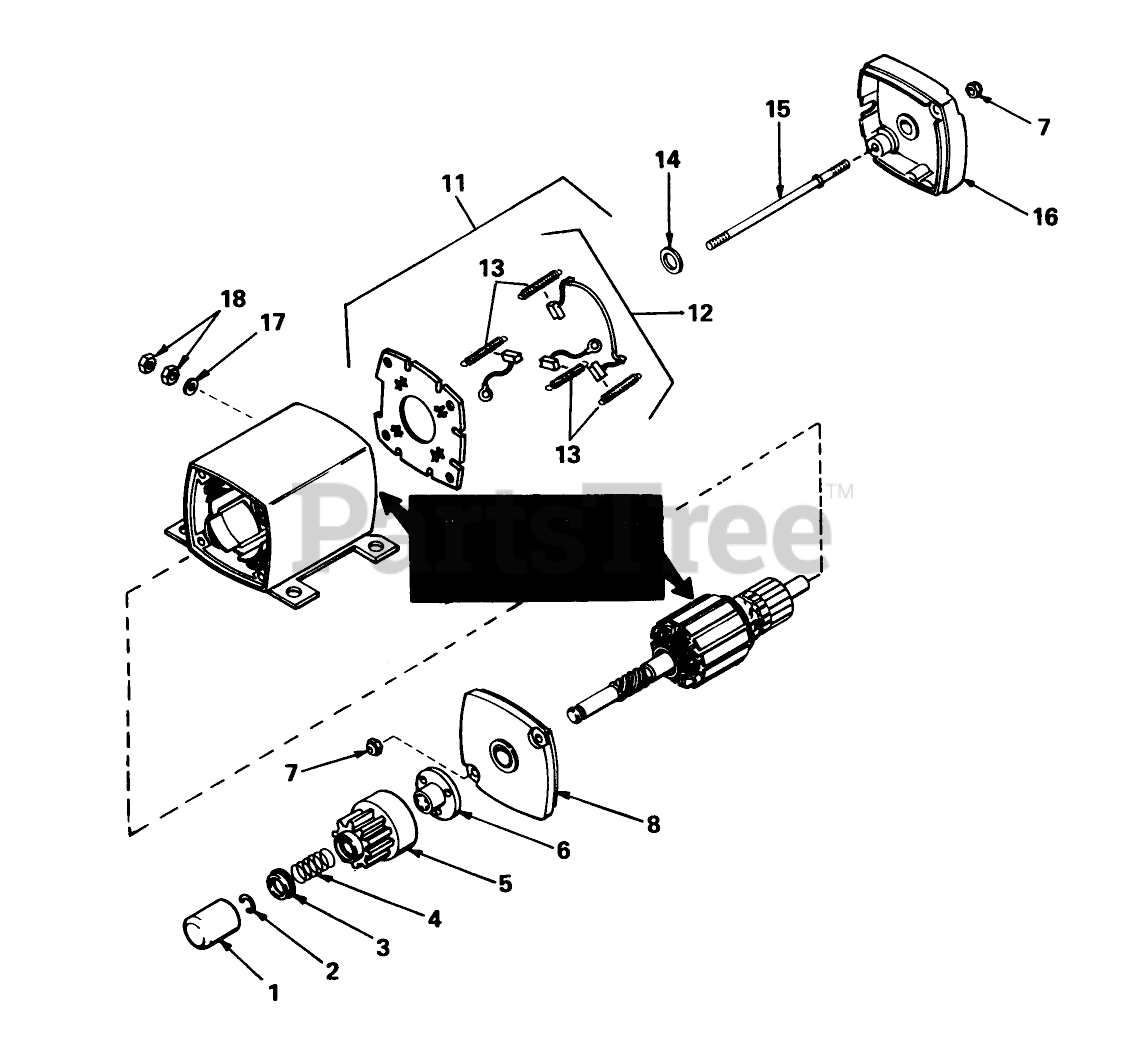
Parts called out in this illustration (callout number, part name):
1	Cover-Dust
2	Ring-Retainer
3	Retainer-Spring
4	Spring-Anti Drift
5	Gear
6	Nut-Engaging
7	Nut-Lock
8	Cap Assy., Drive End
11	Card Assy., Brush (Incl. No. 12)
12	Brush Spring Kit (Incl. 4 pcs. of #13)
13	1545D SUP TO W/3256
14	Washer-Thrust
15	Bolt
16	2035A67 WIZARD W/34
17	Washer
18	Nut-Hex
